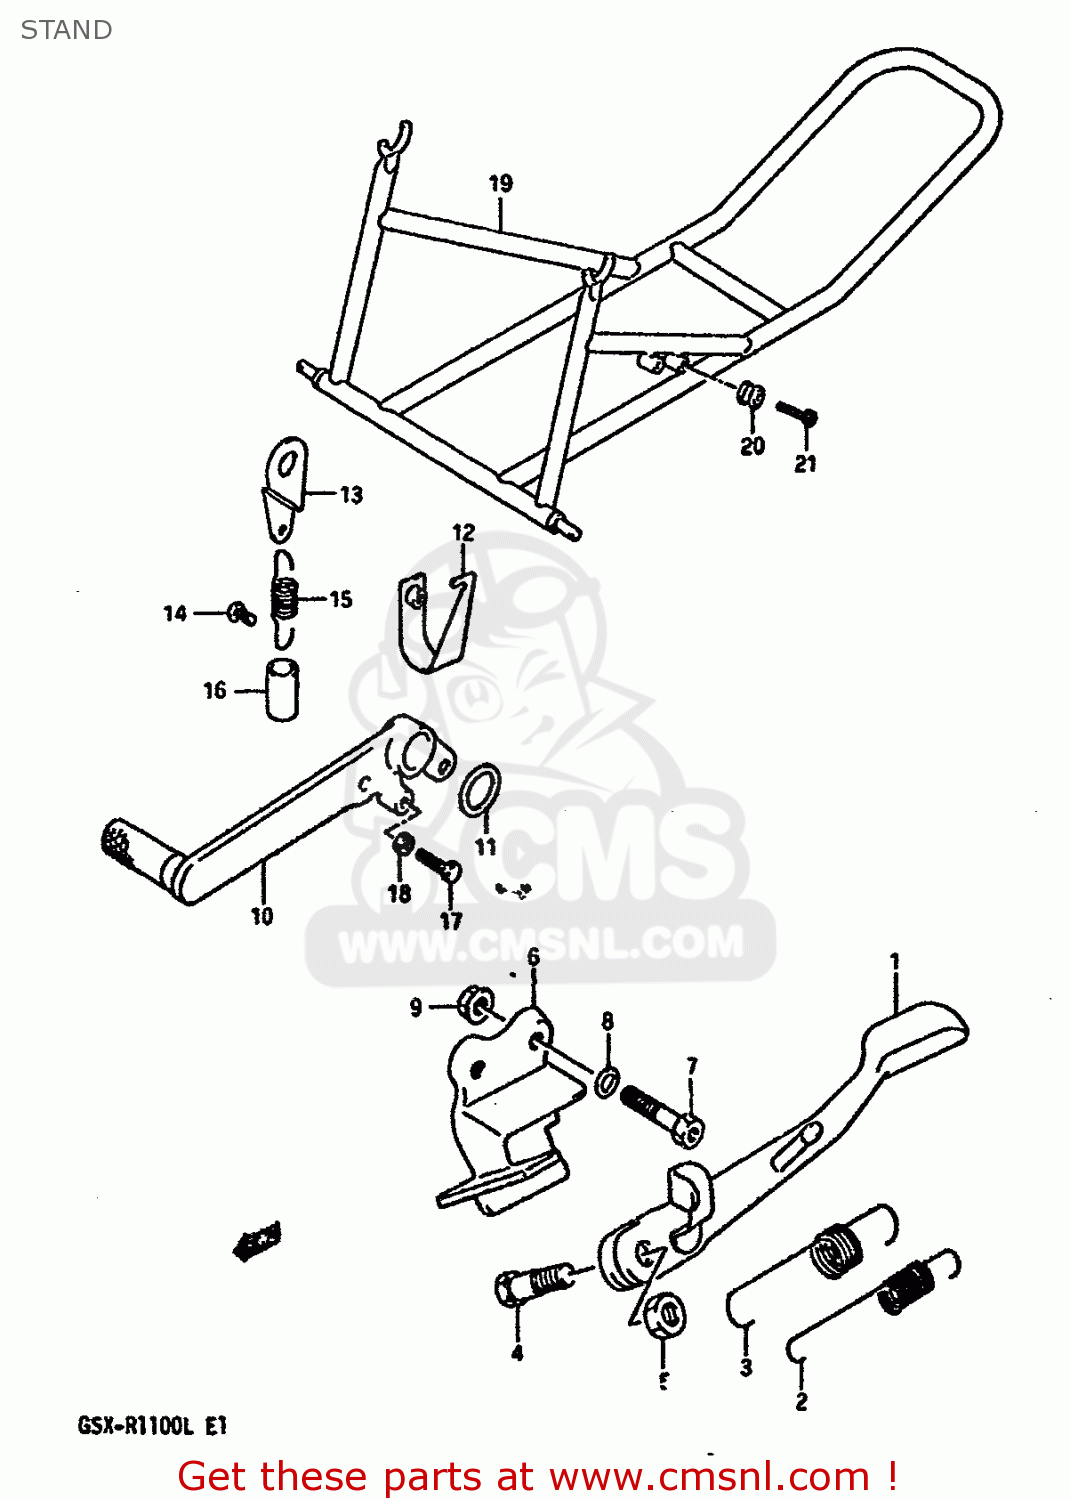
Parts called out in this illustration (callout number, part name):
1	STAND,PROP
2	SPRING
3	SPRING
4	BOLT(10X38)
5	NUT
6	BRACKET,PROP STAND
7	BOLT, FRONT RH
8	WASHER
9	NUT
10	PEDAL,BRAKE
11	WASHER(18X24X1)
12	PLATE,BRAKE SPRING,FRONT
13	BRACKET,STOP SWITCH SPRING
14	SCREW(6X12)
15	SPRING
16	TUBE,BRAKE SPRING GUIDE
17	BOLT
18	NUT
19	STAND ASSEMBLY,REAR
20	HOLDER,STAND
21	BOLT, REAR (8X30)
